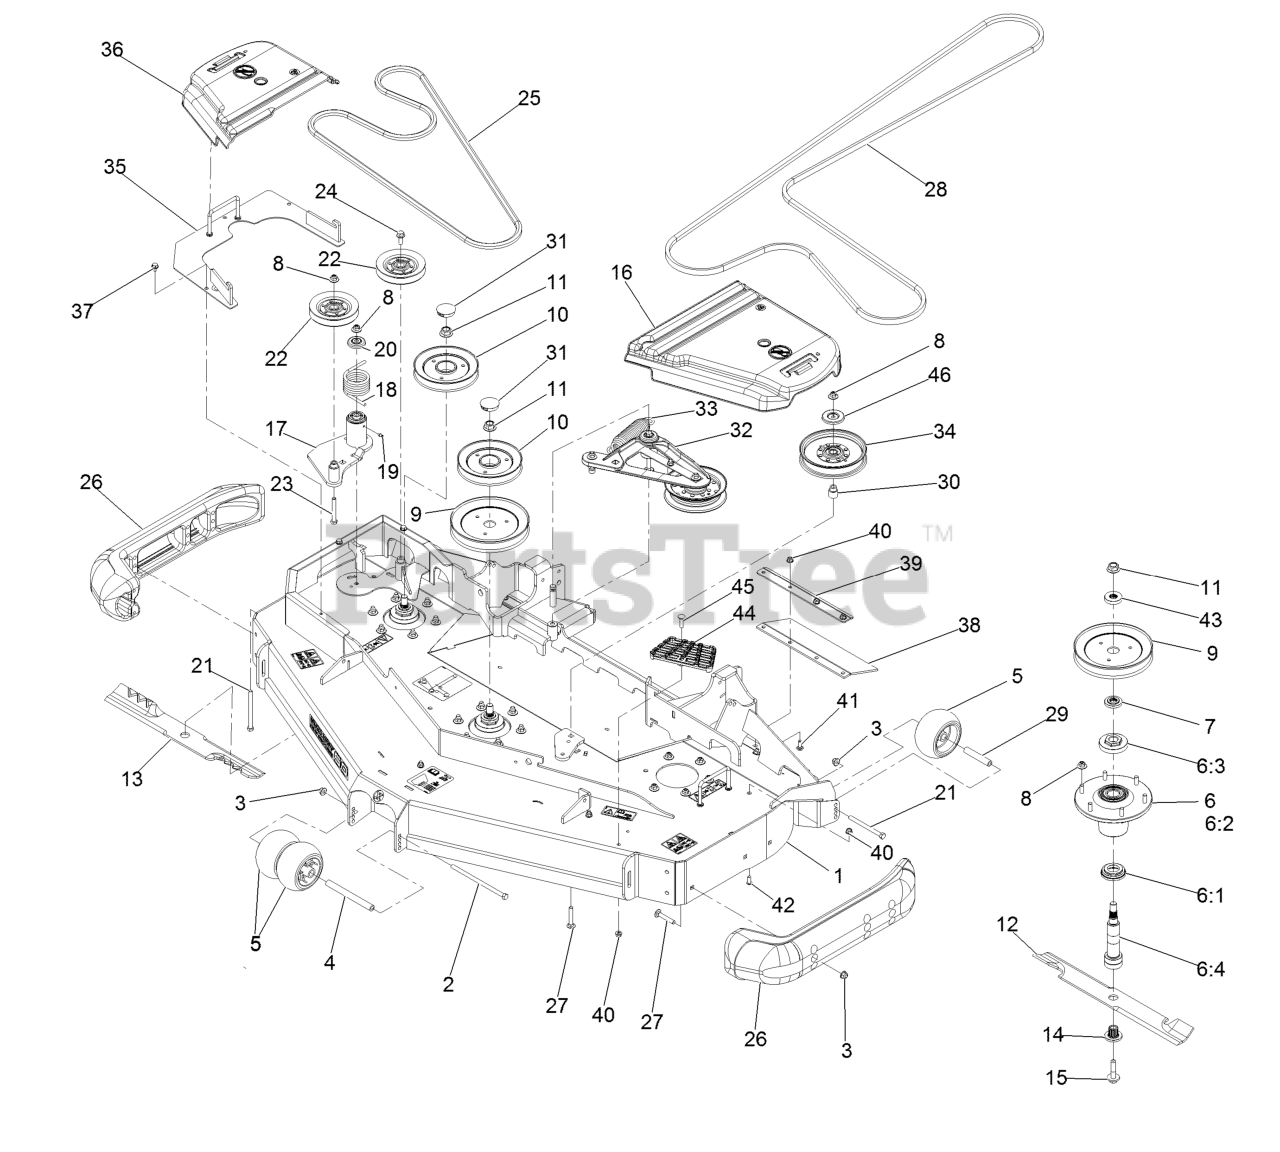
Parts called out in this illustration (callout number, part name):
1	Deck-Rd60 Nlz, W/Decals
2	Screw-HH 3/8-16 X 7 3/8
3	Nut-Nyloc 3/8-16 Flg
4	Spacer-Wheel
5	Roller-Scalp, Anti
6	ASM,Spindle Housing
6:1	Guard, Bottom
6:2	Asm, Cutter Housing
6:3	Nut, Spindle 7/8-14
6:4	Spindle,Double Spline
7	Spacer, Splined Stepped
8	Nut-Nyloc 3/8-16 Flg
9	Sheave,Blade Drive 7.25
10	Sheave-Rd, Reverse Drive
11	Nut-Flange 5/8-18 Centerlock
12	Blade, Low Lift
12	Blade, Notched
12	Blade-Extreme 2, 20.50"
13	Blade-Extreme 2-20.50, Rd60
13	Blade-Low Lift 20.5, Rd60
14	Bushing, Splined
15	Screw-Sems 1/2-20 X 2.19
16	Cover-Belt, LH
17	Idler ASM
18	Spring-Torsion
19	Zerk-1/4-28 Str
20	Guard-Top
21	Screw-HH 3/8-16 X 4-1/2
23	Screw-HH 3/8-16 X 2 3/4
24	Screw-HH Flg 3/8-16 X 1
25	Belt
26	Skid-Bumper, Deck
27	Bolt-Carriage 3/8-16 X 2 1/4
28	Belt
29	Tube-Spanner
30	Bushing, Idler
31	Plug,Black Nylon 1.75
32	Deck Idler ASM
33	Spring-Extension
34	Idler-Pulley, Flat 6.00X1.00
35	Cover-Drive Reverse
36	Cover-Belt, RH
37	Screw-HWH 5/16 X 1/2 Tf
38	Guard-Tire
39	Support-Outer Flap
40	Nut-Nyloc 5/16-18 Flg
41	Bolt-Carriage 5/16-18 X 7/8
42	Screw-Button Head 5/16-18 X 3/4
43	Spacer, Splined
44	Step-Deck
45	Bolt-Carriage 5/16-18 X 1 1/4
46	Shield-Dust
